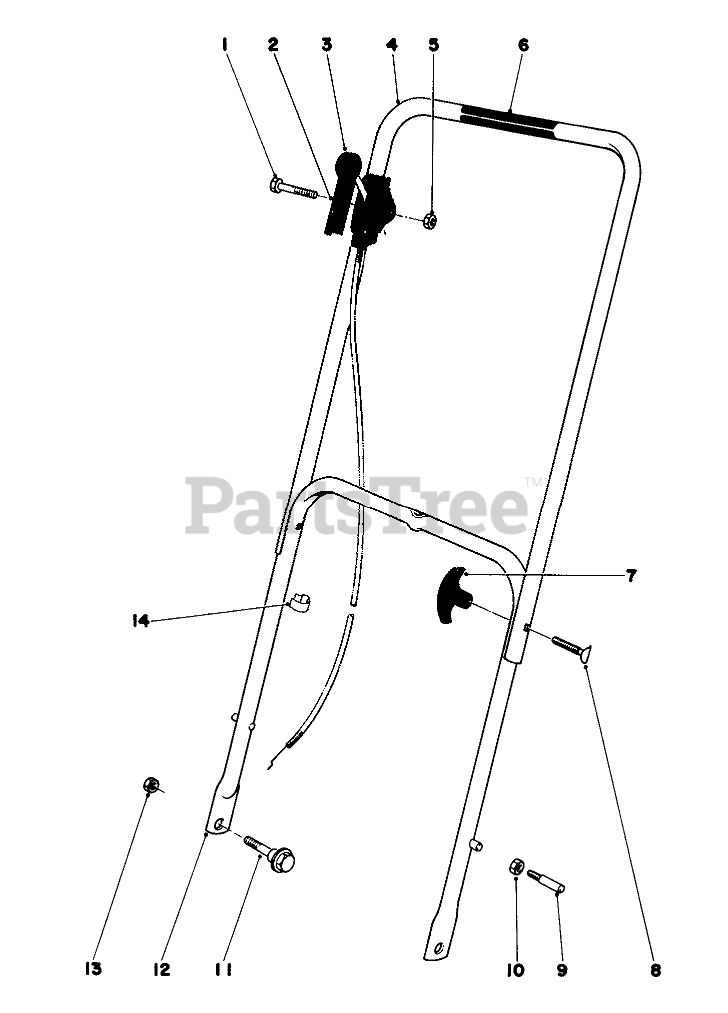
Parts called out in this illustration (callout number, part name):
1	SCREW-HH
2	Decal Throttle Control
3	Throttle Control
4	Upper Handle
5	NUT-LOCK
6	Decal Danger (French & Dutch)
7	Handle Knob
8	HANDLE SCREW
9	HANDLE PIN
10	Nut
11	SCREW-SHOULDER
12	19 LOWER HANDLE ASM
13	Nut
14	BOWDEN CLIP
